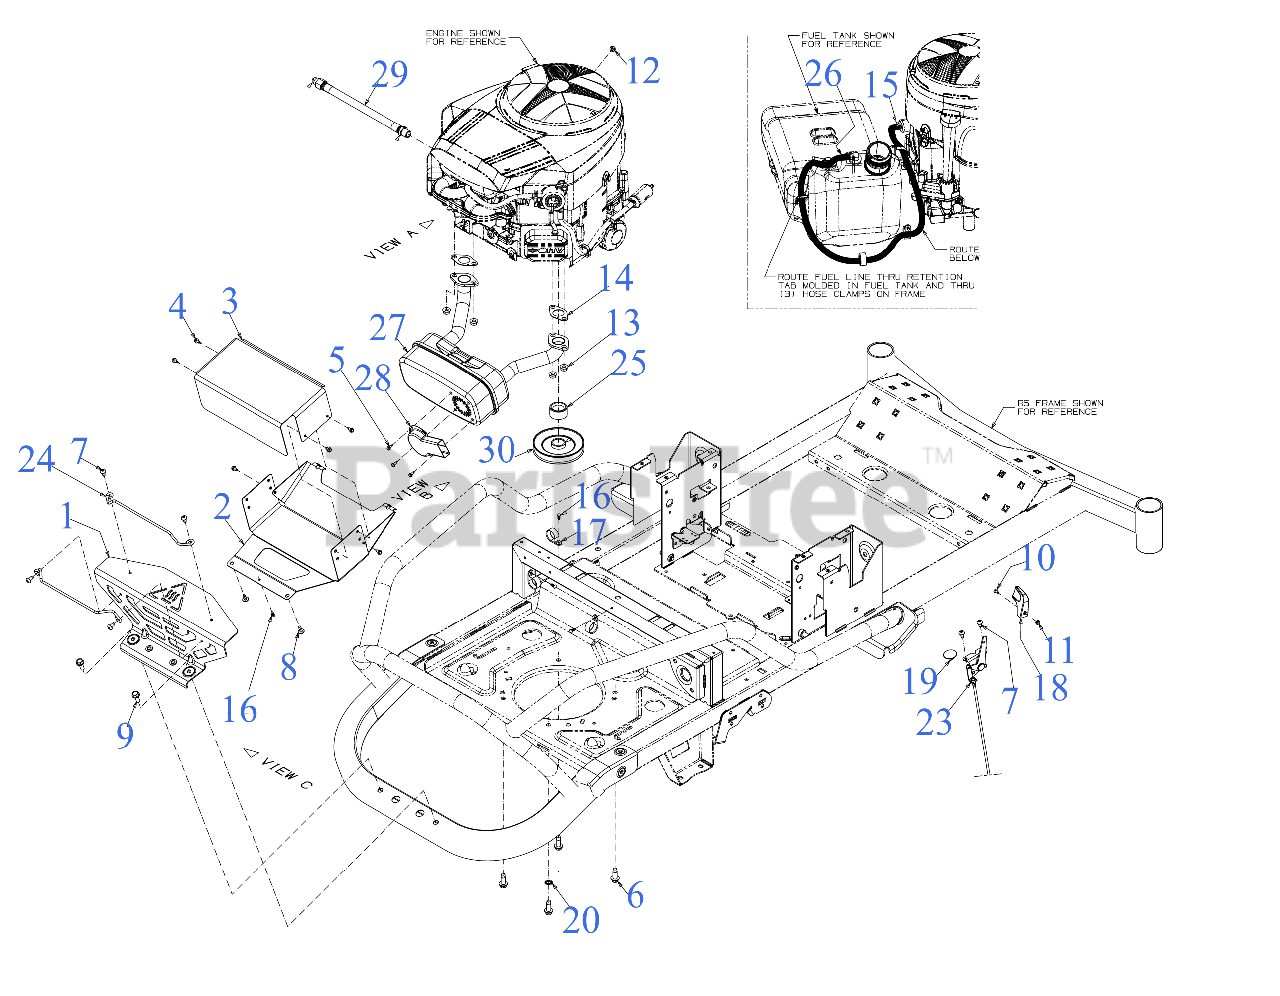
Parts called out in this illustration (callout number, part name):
1	MUFFLER COVER (REAR) (BLACK)
2	MUFFLER SHIELD (LOWER)
3	MUFFLER SHIELD (TOP
4	HEX SCREW AB-TAP #10 x .50
5	HEX SCREW WASHER HD #8-18 x 0.500
6	SCREW 3/8-16 x 1
7	SCREW 1/4-20 x .5
8	SCREW M6-1 x .625
9	SCREW 5/16-18 x .875 GR5
10	SCREW #8-32X.38 LG
11	HEX NUT 8-32
12	HEX NUT 1/4-20
13	HEX FLANGE NUT M8X
14	MUFFLER GASKET
15	HOSE CLAMP 1/20
16	RATCHET CLIP
17	DRAIN HOSE CLAMP
18	THROTTLE CONTROL KNOB
19	CHOKE PLUG
20	LOCK WASHER 3/8
23	THROTTLE CABLE 38"
25	ENGINE PULLEY SPACER
26	FUEL HOSE LOW PERMEATION 45"
27	EXHAUST MUFFLER
28	EXHAUST DELECTOR (LONG)
29	OIL DRAIN HOSE (11.26" 3/8 NPT)
30	TRANSMISSION DRIVE PULLEY
